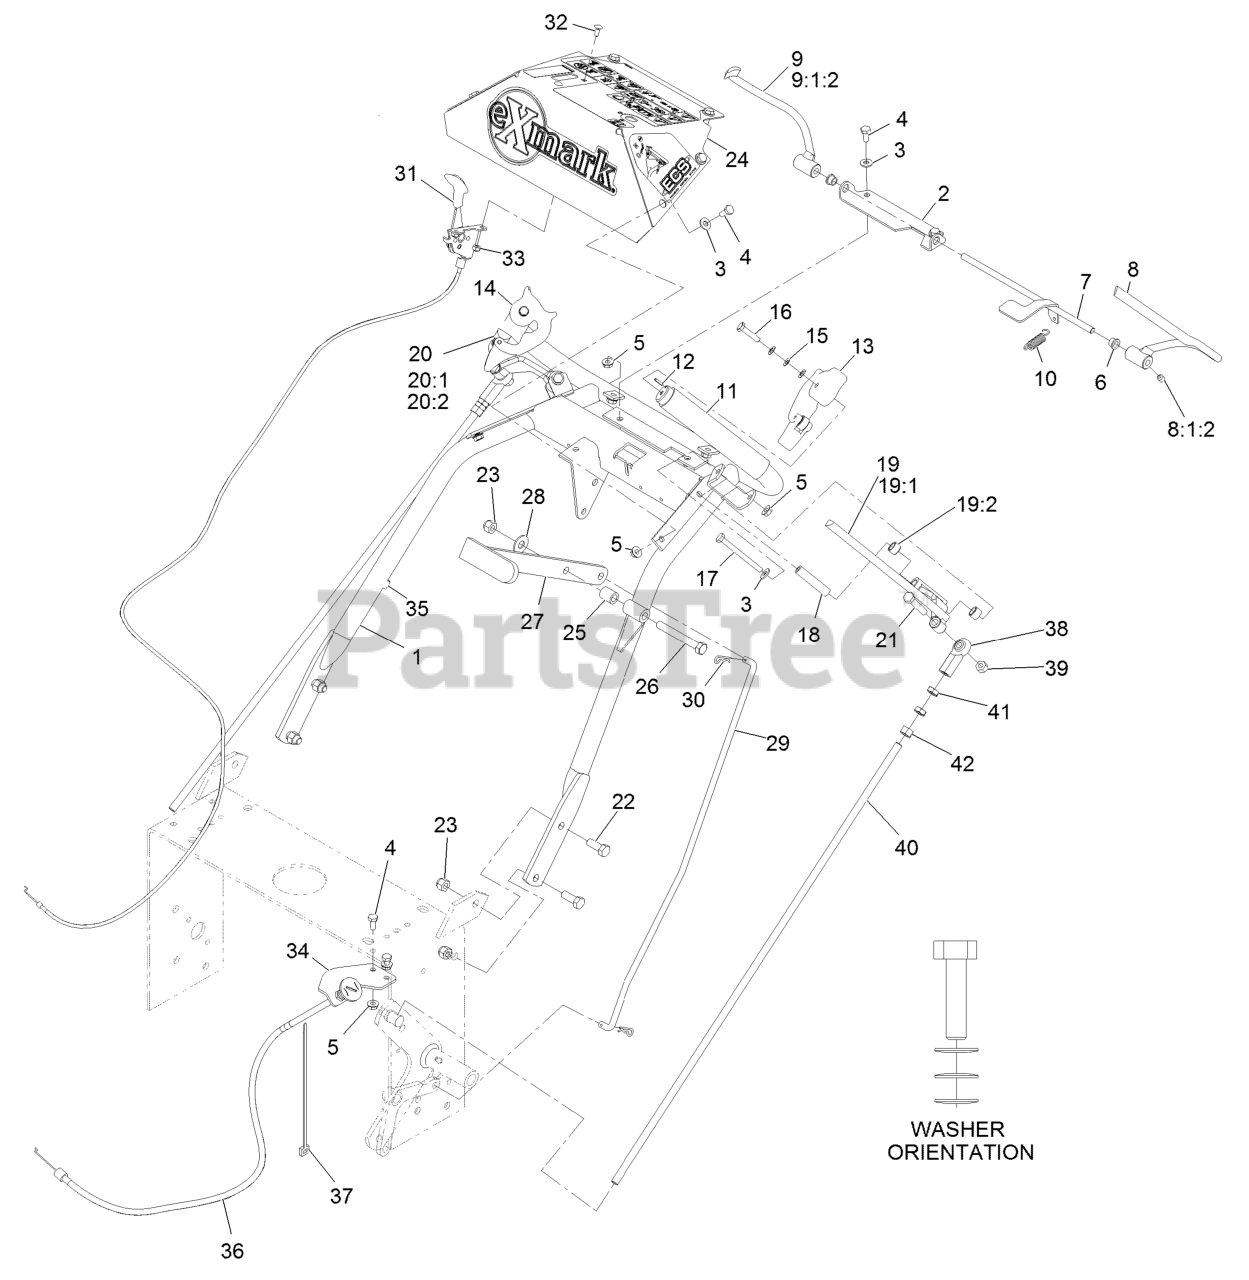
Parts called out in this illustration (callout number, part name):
1	WLD,UPPER ECS HANDLE
2	BRACKET,OPC AXLE
3	WASHER-FLAT
4	SCREW-HH
6	BUSHING-NYLON
7	WLD,OPC LEVER AXLE
8	WLD,LH OPC LEVER
8:1:2	SCREW-SET
9	WLD,RH OPC LEVER
9:1:2	SCREW-SET
10	SPRING-EXTENSION
11	GRIP-BAR, HANDLE
12	PIN-SPRING
13	ASM,LH THUMB LATCH
14	ASM,RH THUMB LATCH
15	WASHER-SPRING
16	SCREW-HH
17	SCREW-HH
18	BUSHING-LEVER, DRIVE
19	DRIVE LEVER-ASM, LH
19:1	WLD,LH DRIVE LEVER
19:2	BUSHING-SLEEVE
20	DRIVE LEVER-ASM, RH
20:1	WLD,RH DRIVE LEVER
20:2	BUSHING-SLEEVE
21	SCREW-HH
22	SCREW-HH
23	NUT-LOCK, NI
24	ASM, CONSOLE W/DECALS
25	BUSHING-LEVER, LIFT
26	SCREW-CARR
27	CLUTCH LEVER-W/GRIP
28	WASHER-FLAT
29	LINKAGE,UPPER BLADE (PLT)
30	PIN-COTTER
31	CONTROL, THROTTLE
31	Control, Throttle
32	BOLT-CARR
33	NUT-LOCK, NI
34	BRACKET-CABLE, CHOKE
35	CLIP-CABLE
36	CABLE-CHOKE
36	Cable-Choke
37	TIE-PLASTIC
38	JOINT-BALL, END
39	NUT-LOCK, NI
40	LINKAGE,DRIVE (PLT)
41	NUT-HJ
42	NUT-HEX
